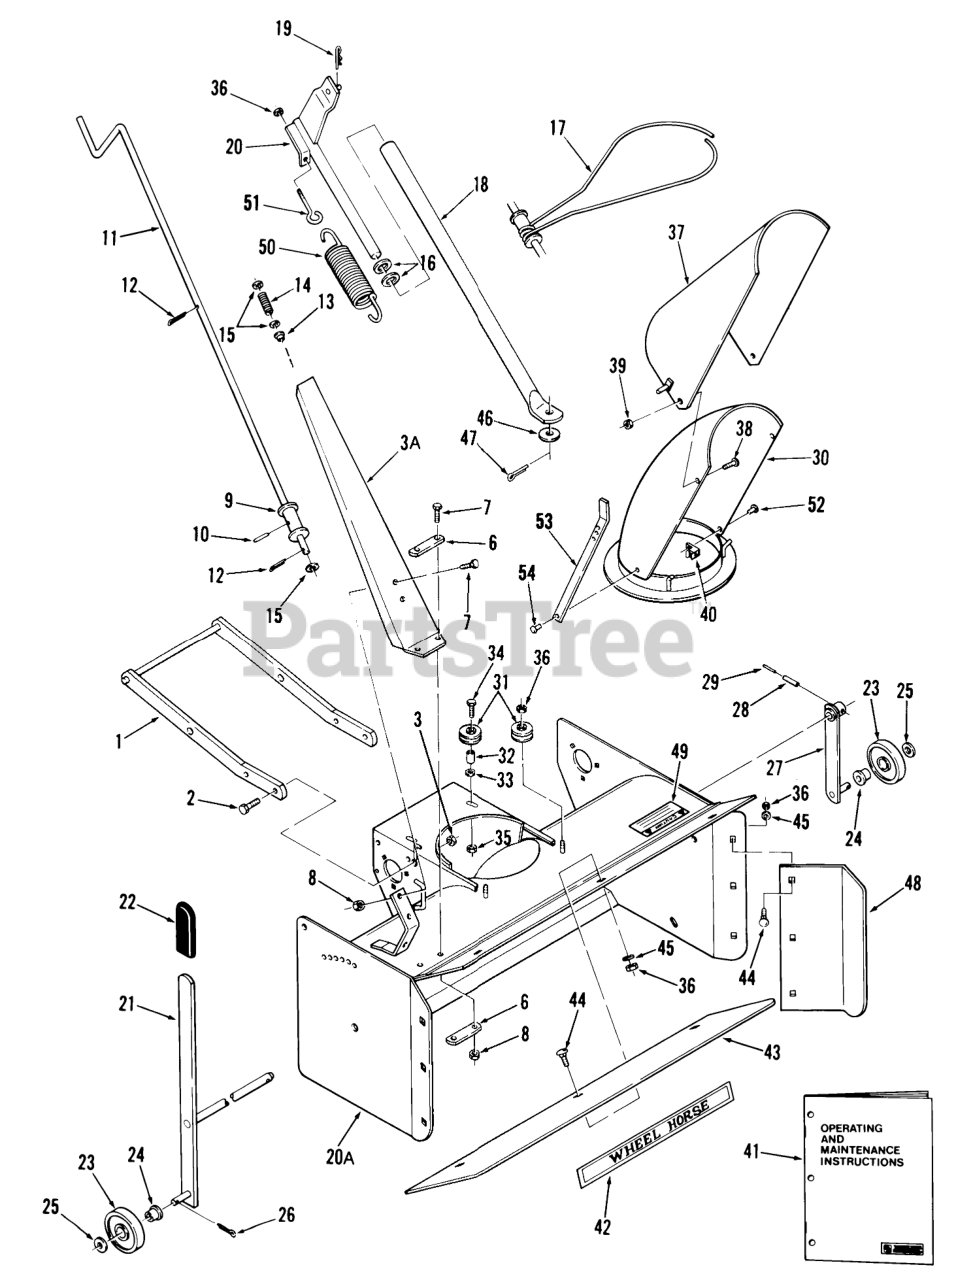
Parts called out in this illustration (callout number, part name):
1	Frame-Mounting
2	Bolt
3	Nut
3A	Crank Support
6	Bar-Reinforcing
7	Bolt
8	Nut
9	ASSY TUBE CRANK R
10	ROLL PIN 1/4 X 1-1/4
11	Crank
12	Pop Rivet
13	NYLINER BUSHING
14	SPRING-COMPRESSION
15	Washer
16	Washer
17	CABLE
18	ASSY LIFT TUBE R
19	Hairpin
20	LIFT ROD ASM
20A	Wrapper Assembly
21	ASSY AUGER SHAFT R
22	GRIP
23	Wheel Assembly (Includes Item 24)
24	Bushing
25	Washer
26	Pop Rivet
27	Wheel Support
28	ROLL PIN 1/4 X 1-1/4
29	PIN-SPIROL
30	S/A SHROUD R
31	Roller
32	SPACER
34	Bolt
35	Nut
36	NUT
37	Deflector
38	MACH. SCREW
39	Nut
40	CLAMP
41	Operating and Maintenance Instructions
42	DECAL-WHEEL HORSE
43	Plate
44	Bolt
45	Washer
46	WASHER
47	Cotter Pin
48	Plate
49	Decal-Caution
50	SPRING
51	EYEBOLT
52	RIVET-4
53	ARM R
54	RIVET
